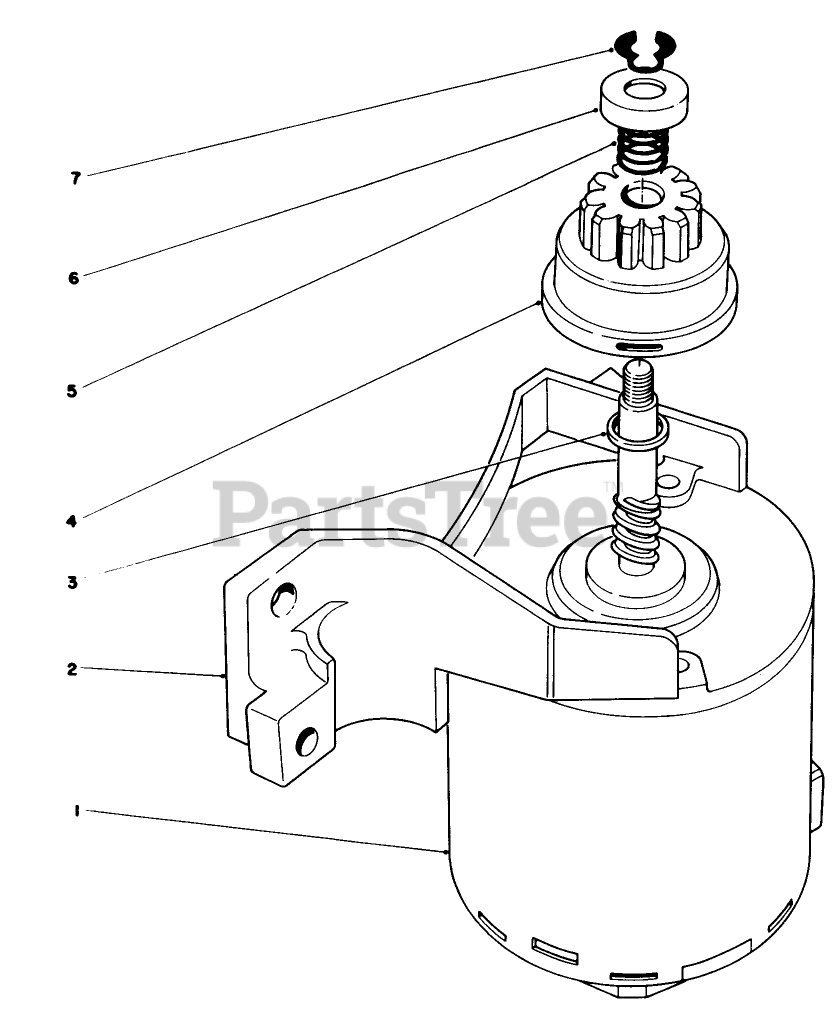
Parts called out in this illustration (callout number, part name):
1	END FRAME W/BRUSH
2	BRKT END FRAME
3	SPACER
4	PINION ASM
5	COMPRESSION SPRING
6	PINION STOP
7	RING-RETAINING
